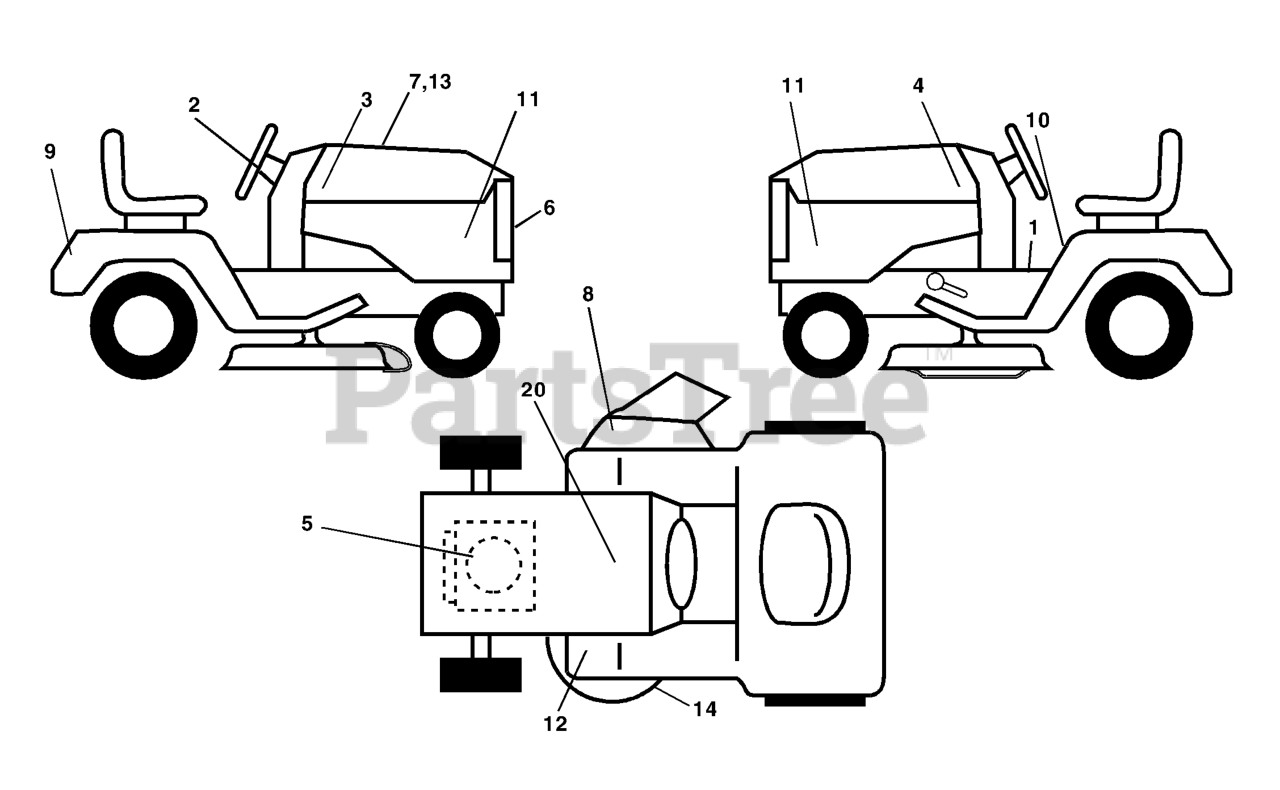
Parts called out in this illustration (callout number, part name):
2	DECAL.WHEEL.STEERING.HUSQ.PERM
3	DECAL HOOD RH
4	DECAL HOOD LH
5	DECAL ENGINE
6	DECAL.GRILLE.HUSQ
7	DECAL, 'REPLACEMENT PARTS'
8	DECAL.WARN.KEEP.HAND.AWAY
9	DECAL, FENDER
10	DECAL FENDER DANGER
11	DECAL HOOD SIDES
12	DECAL CLUTCH/BRAKE
13	DECAL HOOD CUST. RESP.
14	DECAL V-BELT SCHEMATIC
20	DECAL BTRY SYMBOLS
